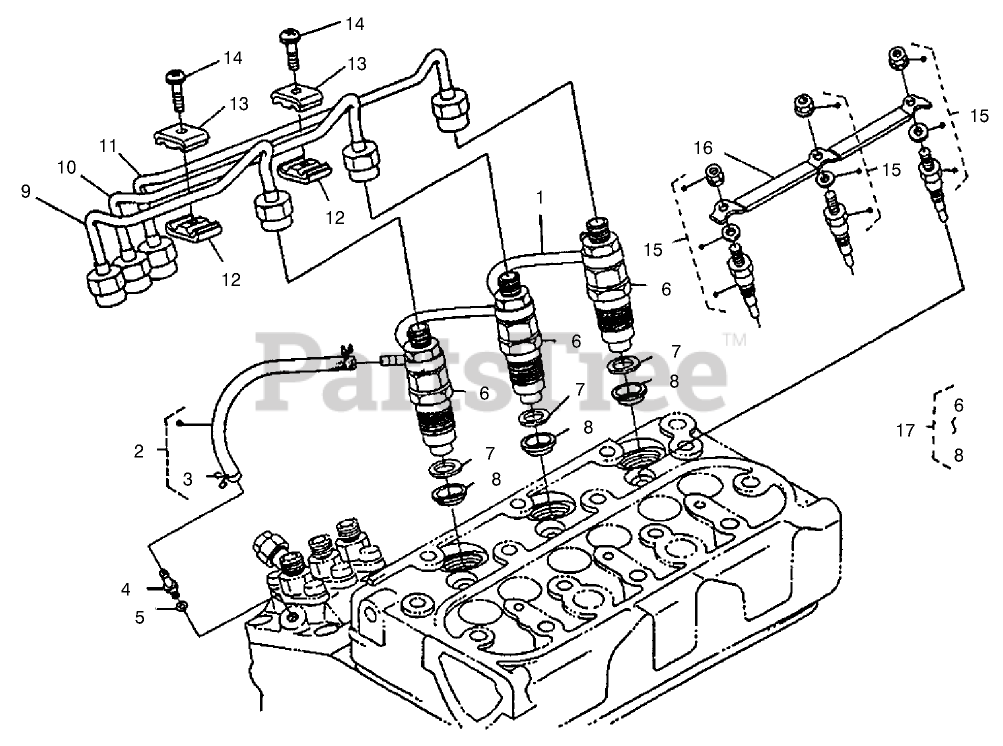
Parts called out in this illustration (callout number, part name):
1	ASSY PIPE, OVER FLOW (S/N 497380)
1	OVER FLOW PIPE ASM
2	OVERFLOW PIPE ASM
3	CLIP-PIPE
4	SCREW-BLEEDER, AIR
5	GASKET
6	NOZZLE HOLDER ASM
7	GASKET
8	SEAL-HEAT
9	PIPE, INJECTION (S/N 512877)
9	PIPE-INJECTION
10	PIPE, INJECTION (S/N 512877)
10	PIPE-INJECTION
11	PIPE, INJECTION (S/N 512877)
11	PIPE-INJECTION
12	CLAMP-PIPE
13	CLAMP-PIPE
14	SCREW (W/WASHER)
15	PLUG-GLOW
16	CORD-PLUG, GLOW
17	NOZZLE HOLDER KIT
